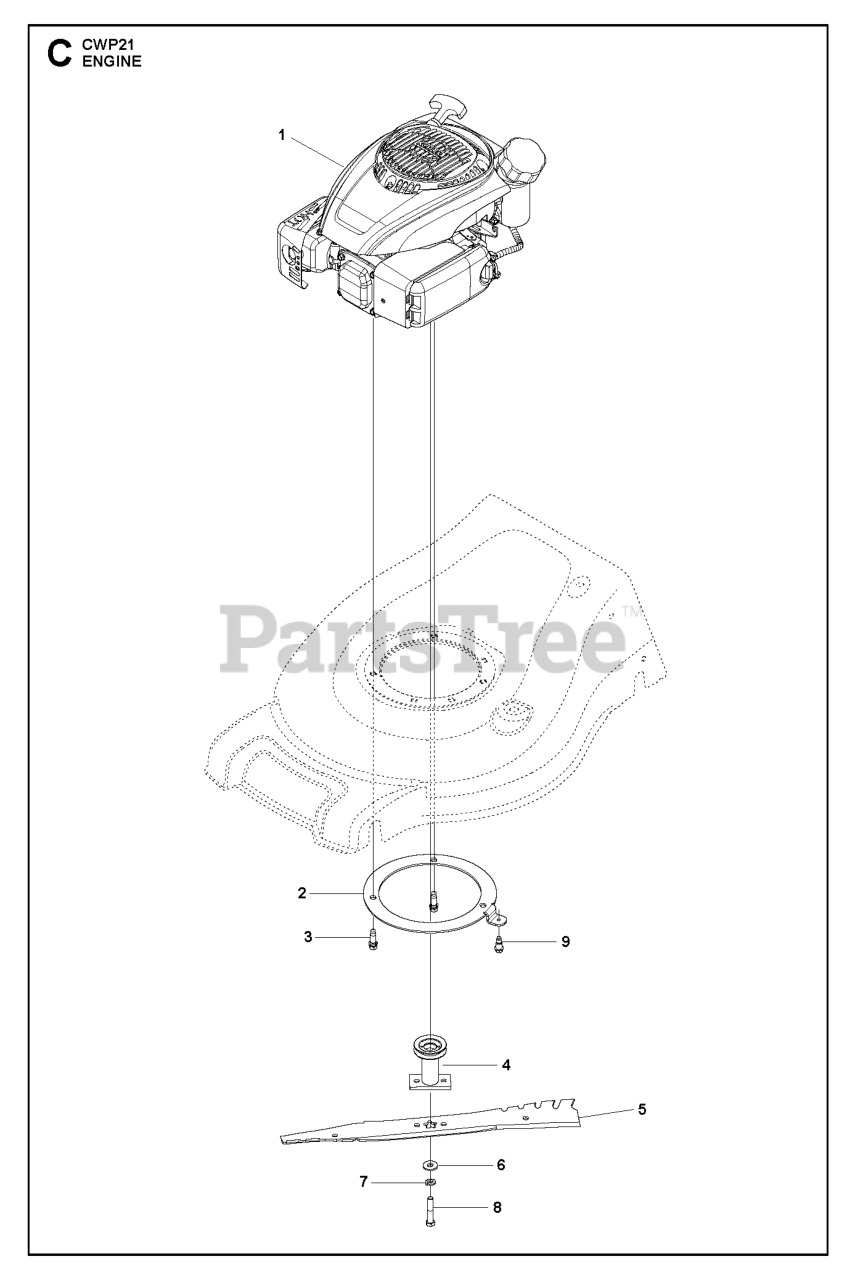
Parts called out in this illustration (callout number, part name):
2	MOUNTING PLATE BOTTOM ENGINE R
3	BOLT 3/8-16X1-1/8
4	ADAPTER.BLD.25M.2P.AW/RW/21EFF
5	BLADE.21.REAPER.WO/NOTCHES
6	WASHER,HARDEN
7	LOCKWASHER
8	BOLT.ENGINE.PULLEY
9	BOLT SHOULDER_1/4-20_TRILOB
